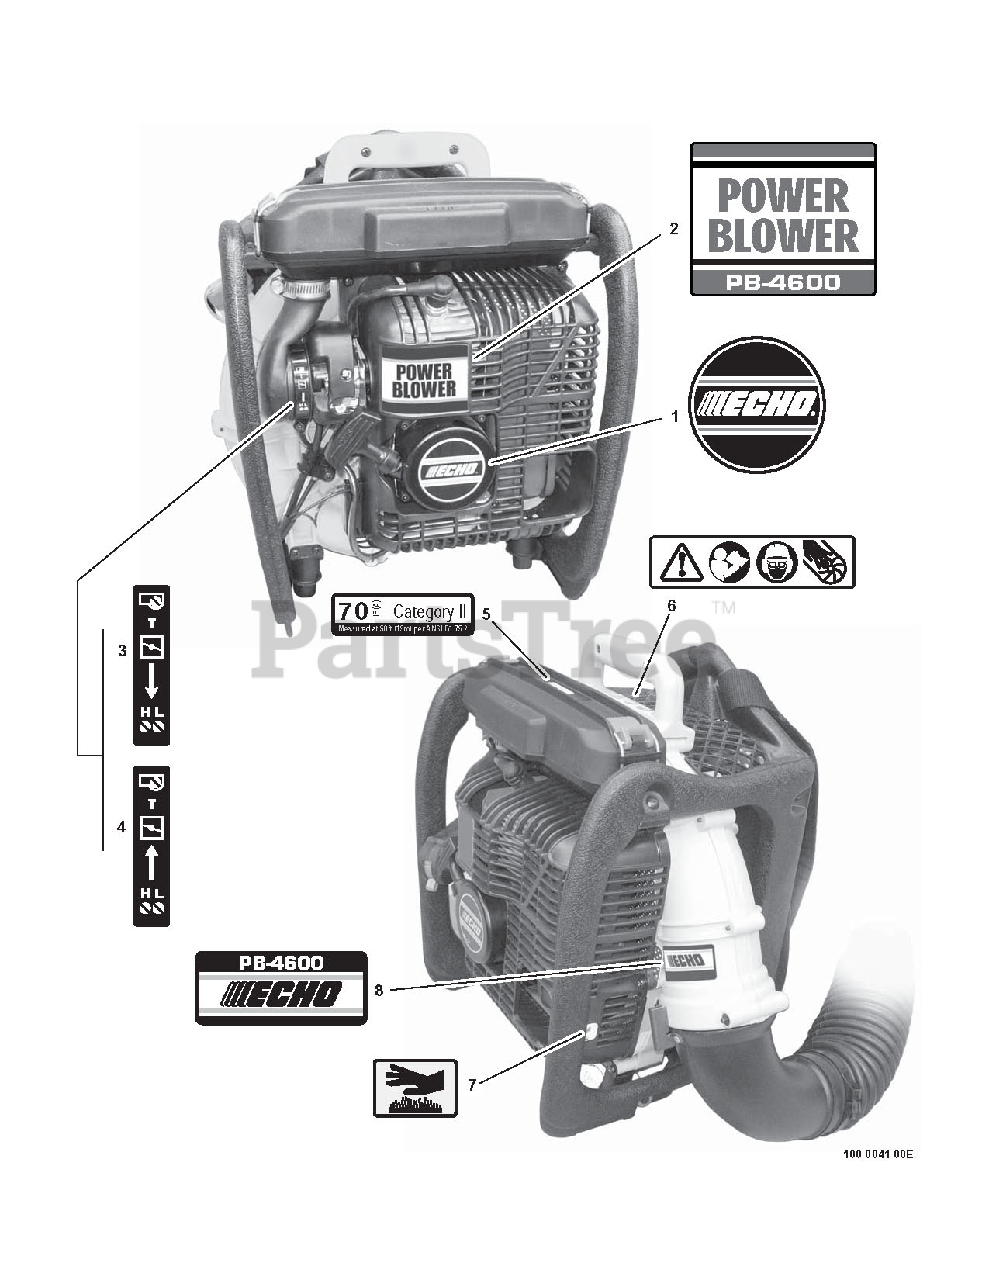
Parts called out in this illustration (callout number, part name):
1	LABEL - ECHO
2	LABEL - MODEL PB-4600
3	LABEL - CHOKE
4	LABEL - CHOKE
5	LABEL - NOISE
6	LABEL - CAUTION
7	LABEL - HOT SURFACE
8	LABEL - MODEL PB-4600
